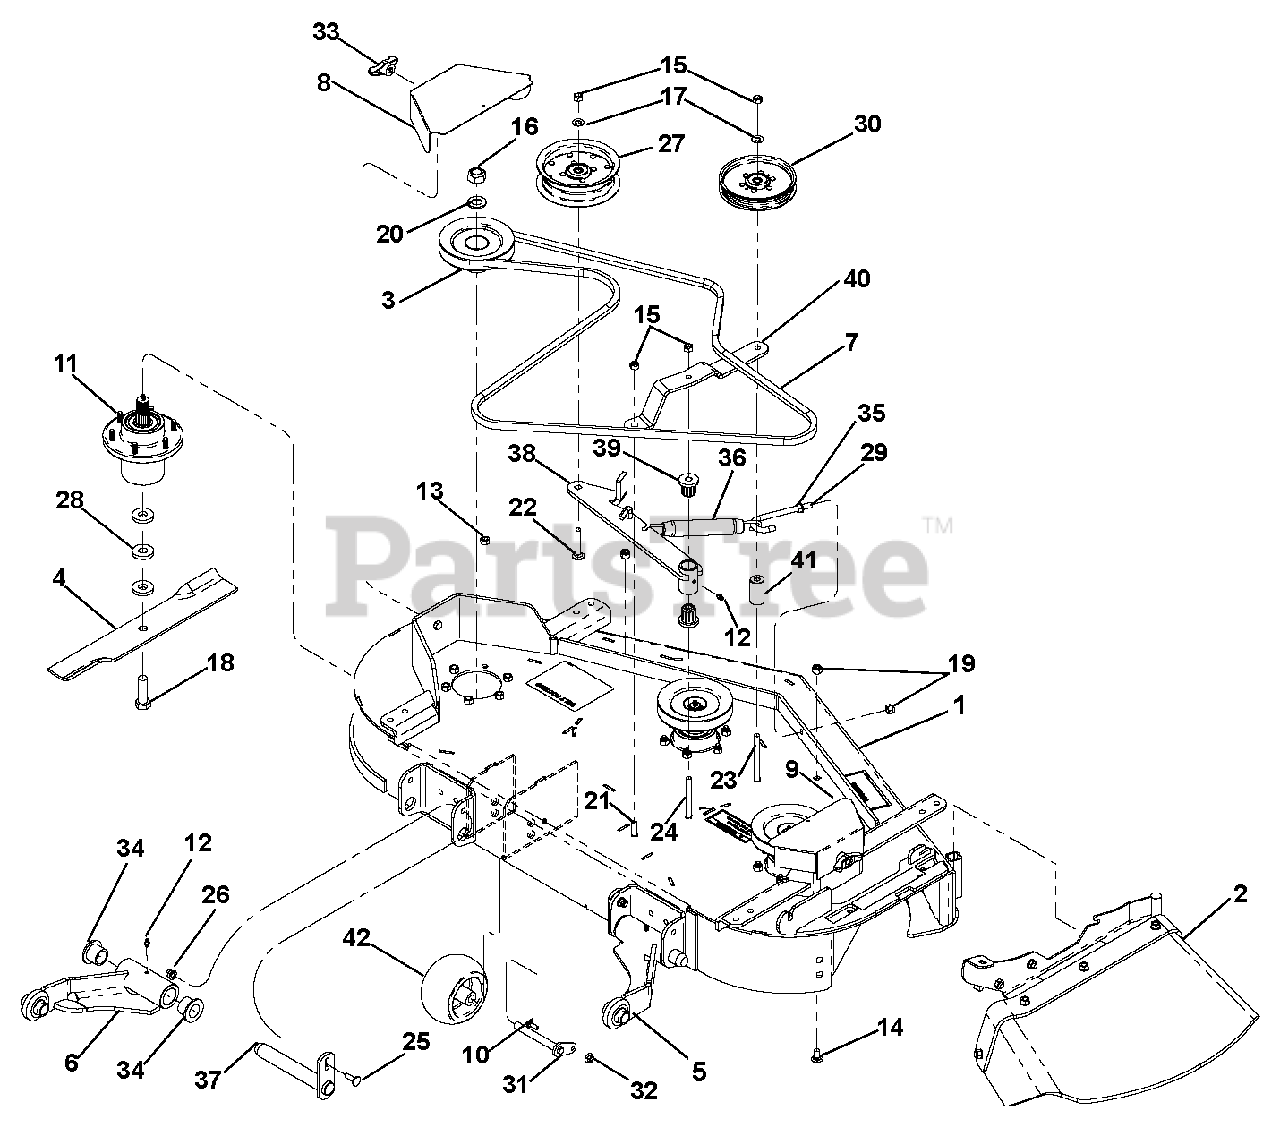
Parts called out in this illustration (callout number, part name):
1	Assembly, 48" Float Deck with Decals (994100)
1	Deck, with Decals Gravely 52FL (994103)
2	Assembly, 48 Flat Discharge Shield (994100)
2	Assembly Discharge Shield (994103)
3	Pulley, Spline Spindle Offset (994100)
3	Pulley, Spline Spindle Offset (994103)
4	Blade, 16.50 x .80 Lift (994103)
4	Blade, 18.00 x 80 Lift (994100)
5	Arm Weldment, RH 48" (994100)
5	Arm Weldment, RH 52" (994103)
6	Arm Weldment, LH 48" (994100)
6	Arm Weldment, LH 52" (994103)
7	Belt, HB 98.6 EL AMD (944100)
7	Belt, HB 109.3 EL AMD (944103)
8	Left Hand Deck Belt Cover (994100, 994103)
9	Right Hand Deck Belt Cover (994100)
10	Bolt, 1/4-20 x .750
10	Bolt, 1/4-20 x 1.00
11	Assembly, Spindle Housing
12	Fitting, Lubrication
13	Nut, 3/8-16 Standard Hex Grade 5
14	Bolt, 3/8-16 x .750
15	Locknut, Crown 3/8-16
16	Locknut, Crown 3/4-16
17	Washer, Flat .406 x .813 x .065
18	Bolt, Hex 5/8-11 x 2.00
19	Locknut, Nyloc 3/8-16
20	Washer, .75 x 1.3125 x .113
21	Bolt, Round Head Square Neck
22	Bolt, 3/8-16 x 2.25
23	Bolt, Round Head 3/8 x 4 SHTNK
24	Bolt, .38-16 x 3.50
25	Bolt, Right Hand Square Neck, M8 x 1.25
26	Locknut, Nyloc Flange, M8 x 1.25
27	Pulley, Flat 5.00 x .375 W/ BRG
28	Washer, Flat, .630 x 1.50 x .250
29	J-Bolt, .38-16 x 4.00
30	Pulley, Flat Idler
31	Pivot, Retainer Weldment
32	Nut-1/4" Flange Prevailing Tor
33	Knob, .38-16 Insert
34	Bearing, Flanged
35	Locknut, 3/6-16
36	Spring, External
37	Pin, Welded
38	Arm, Idler
39	Bearing, Flange M10 x M25 x M27 Fluted
40	Strap, Idler Pulley
41	Spacer Assembly
42	Wheel, Gage
